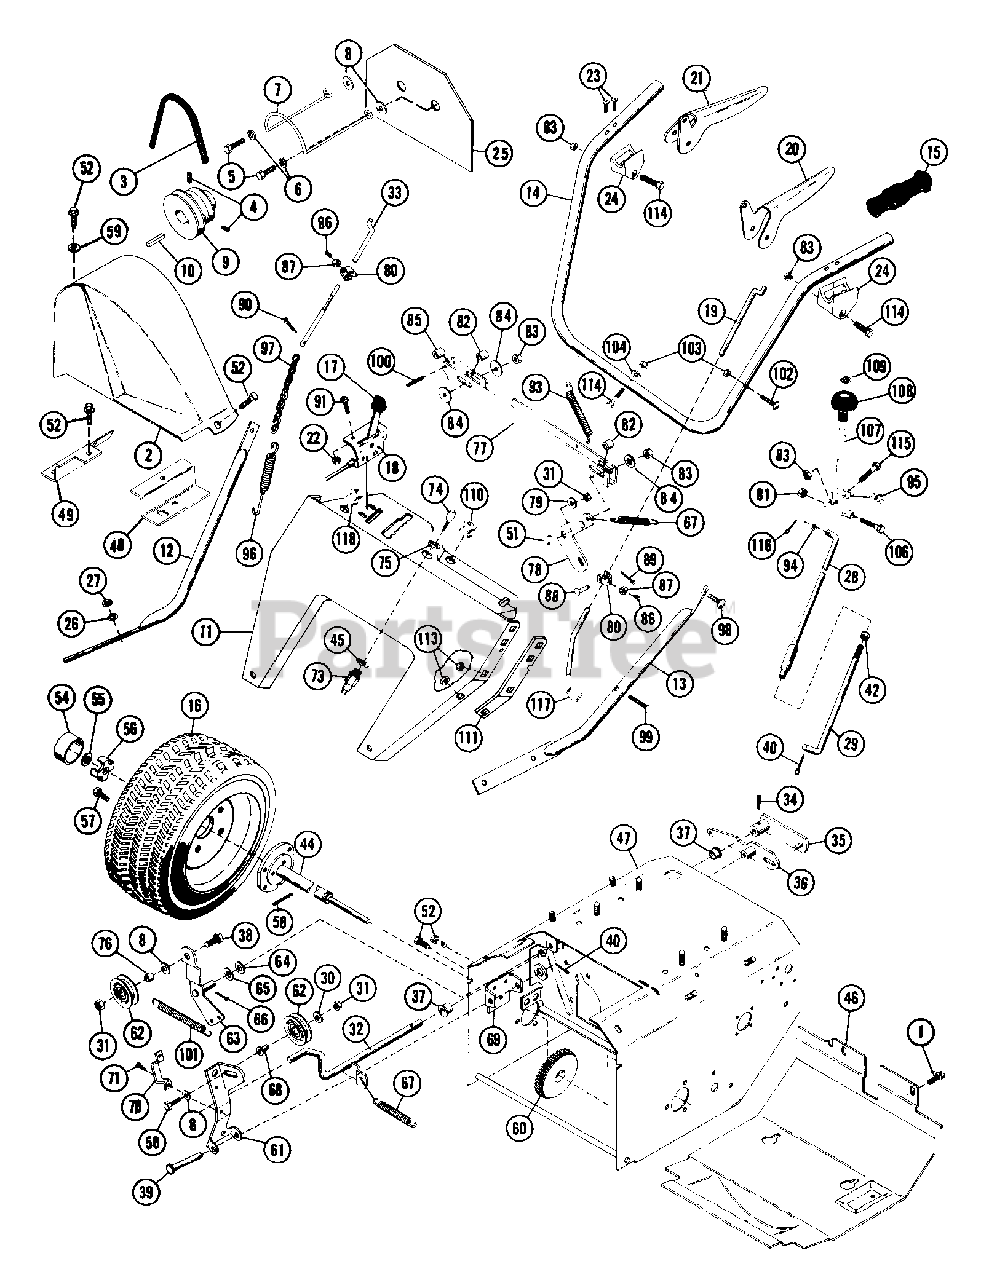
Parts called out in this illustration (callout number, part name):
1	BLT-SERHFWH .31-18X.50 PL
2	BELT COVER
3	V-BELT, 3L-RAW EDGE
4	SCR-SET .32-18X.38 SKHCUPNL OH
5	TIE DOWN
6	WSHR-LK-EXT .313X.030 PL
7	BELT FINGER
8	WSHR-FL-STL .38X.875X.083 PL
9	SHEAVE, ENGINE
10	KEY-STR .25X1.75X.25
11	HANDLEBAR PANEL
12	LOWER HANDLEBAR RH
13	LOWER HANDLEBAR LH
14	UPPER HANDLEBAR LW
15	GRIP
16	TERRA TIRE & WHEEL ASSEMBLY
16	TIRE 16X6.50-8 2 PLY
18	THROTTLE CONTROL
19	CLUTCH ROD
20	TRACTION CLUTCH HANDLE WITH DE
21	ATTACHMENT CLUTCH HANDLE
22	NUT-KEPS 10-24 PL
23	SCR-TAP 12-14X1.50 CROVH PL BT
24	HANDLE PIVOT
26	WSHR-LK .375X.115 HVY PL
27	NUT-HEX .375-16
28	UPPER SHIFT ROD
29	LOWER SHIFT ROD
30	WSHR-FL-STL.312X.734X.065PL
31	NUT-LK .312-18 GR A PL
32	ACTIVATING SHAFT
33	ATTACH CLUTCH ROD
34	PIN-ROLL .156X.88
35	LEVER CLUTCH
37	BSHG-FLG.500X.625X.312X.750NY
38	BLT-HEX .31-18X1.00 PL GR 2
39	PIN-CLEV .309X2.25
40	PIN-COTR .09X.75 PL
42	NUT-HEX .312-24 PL
44	R H AXLE
45	WSHR-LK-INT .625X.045 PL
46	BOTTOM COVER
47	TRACTOR FRAME
48	L.H. SUPPORT
49	R.H. SUPPORT
50	BLT-HEX .31-18X1.25 PL GR2
51	SPACER BUSHING .5 X .32 X .163
52	BLT-SERHFWH .25-20X.50 PL
53	WSHR-FL-STL 1.140X1.718X.134
54	HUB CAP
55	PUSHNUT
56	SPINDLE CUP
57	BLT-WHL .50-20X.75 GR5 PL
58	PIN-ROLL .188X1.50
59	WSHR-FL-STL .268X.562X.046 PL
60	DIFFERENTIAL ASSEMBLY
61	ARM, IDLER
62	IDLER
63	IDLER ARM
64	WSHR-FL-STL .382X.812X.023 PL
65	WAVE WASHER .406X.750X.063FH
66	PIN-COTR .12X1.0 PL
67	SG-TENS .062X.43X5.75 WLD 20
68	SPCR, BRG .315X.50X.688X.281
69	BRACKET
70	RETURN CLIP
71	SCR-TAP 10-24X.375 HWH PL TR
73	SWITCH & KEY SET ASSEMBLY
74	KEYS
75	NUT .625-32 ALUM
76	SPACER .50 X .32 X .42
78	BELLCRANK
79	WSHR-FL-STL .328X.875X.062 PL
81	NUT-LK .312-18 GR A PL
82	BSHG-SLV .250X.375X.640
83	NUT-LK-CTR .250-20 PL
84	WSHR-FL-STL .281X1.250X.048PL
85	BSHG-SLV .188X.500X.480
86	SCR-SET .25-20X.75 SKHCUP OH
87	NUT-HEX JAM .25-20 YWZC
88	CLEVIS PIN
89	PIN-HAIR INT .06X.18X.77
90	PIN-COTR .12X.50 PL
91	SCR-MCH 10-24X.50 SLRH BL
93	SG-TENS .035X.45X2.75 WLD 3.5
95	SG-TENS .125X.50X1.38
96	SG-TENS .091X.56X6.12 WLD 40
97	CLUTCH CHAIN
98	BLT-RDHDSQNK .31-18X.75 PL BL
99	BLT-RDHDSQNK .31-18X1.50 PL BL
100	PIN-ROLL .188X.88
101	SG-TENS .080X.73X3.06 WLD 20
102	BLT-RDHDSQNK .25-20X1.50 PL BL
103	NUT-LK-FLG .250-20 PL
104	WSHR-FL-STL .265X.500X.087 PL
106	BLT-HEX .31-18X2.50 PL GR2
107	ROD
109	RG-RTNG-EXT .500X.015
110	SNAP BUSHING
111	R H STIFFENER
111	L H STIFFENER
113	NUT-FLG. .312-18 PL
114	BLT-HEX .25-20X1.50 PL GR5
115	BLT-HEX .25-20X1.00 GR2
116	PIN-COTR .12X.75 PL
118	SNAP BUSHING-.437
